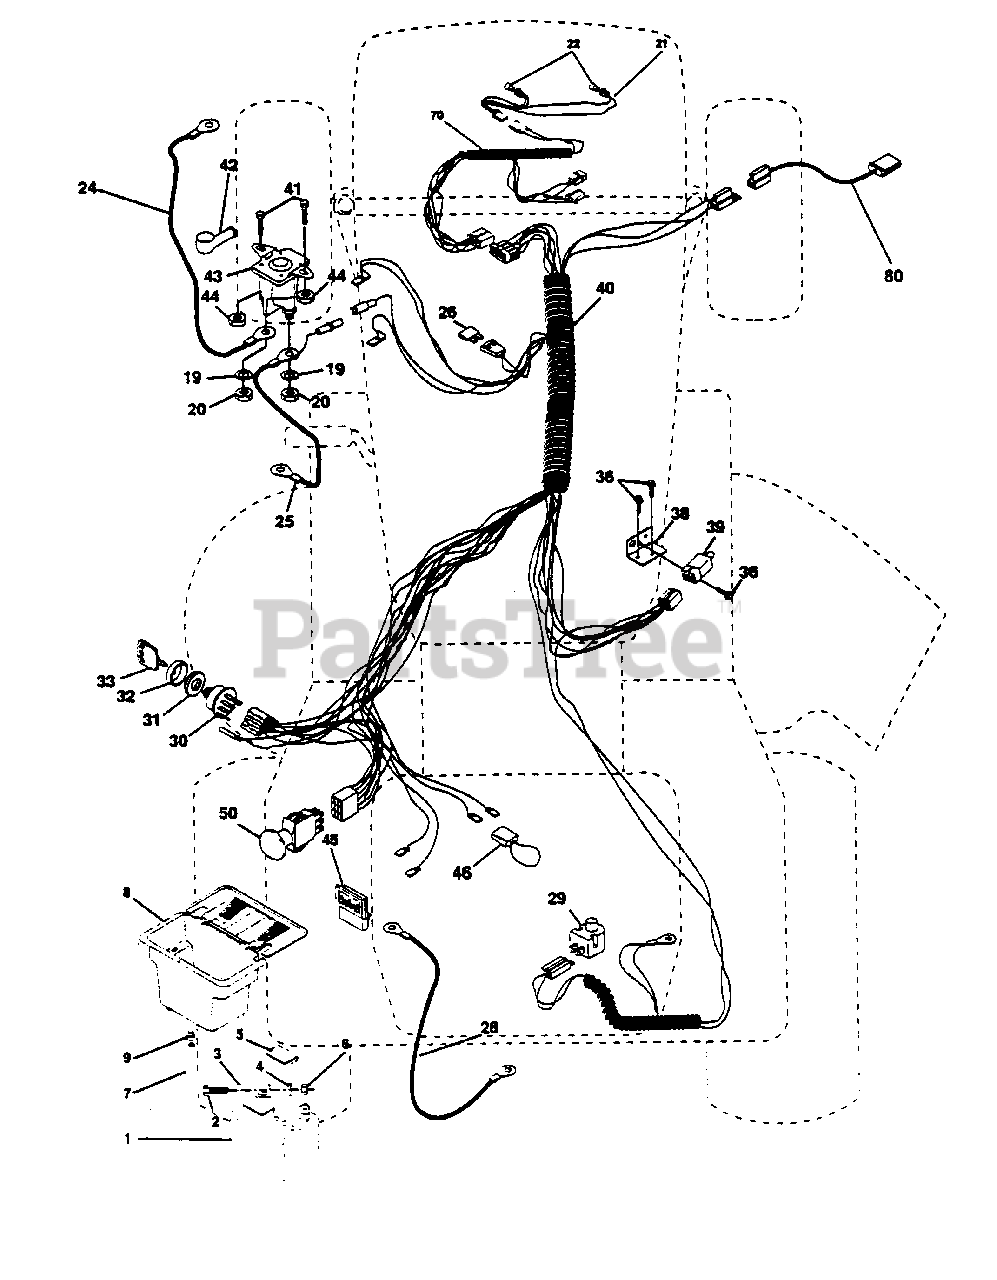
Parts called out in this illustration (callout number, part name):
1	Battery 12 Volt 25 Amp
2	Bolt Hex Hd 1/4-20unc X 3/4
3	Washer 9/32 X 5/8 X 16 Ga
4	Washer Lock Hvy Helical 1/4
5	Caps Battery 20/25/30 AMP
6	Nut Fin Hex 1/4-20 Unc
7	Tube Plastic 12"
8	Battery Case W/2 Holes W/Btry
9	Clamp Hose Olive
19	Washer Lock 1/4
20	Nut Jam Hex 1/4-20 Unc
21	Hamess Asm Light w/4152J
22	Bulb Light #1156
24	Cable Battery 6 Ga 11"red
25	Cable Battery 6 Ga 44"red W/16 Wire
26	Fuse 30 AMP Auto Green
28	Cable Ground 6 Ga 12"black
29	Switch Plunger Nc Gray
30	Switch Ign 4 Pos.
32	Cover Sw Key Blk 1 25 Text SLT
36	Screw Tap Hex #10-24unc X 1/2
38	Bracket Switch Clutch
39	Switch Intlk Clutch Gry 4 Term
40	Hamess Ignition Elec HM LT P/L
41	Bolt Fin Hex 1/4-20 x 1/2
42	Cover Terminal Red
43	Solenoid
44	Nut Keps Hex 1/4-20 Unc
45	Ammeter rectangular
46	Protection Wire Loop (Hourmeter)
50	Switch PTO 3 pdt. delta
70	Hamess Eng. P/L B&S 140 HV Du HL
80	Hamess Clutch EVX
